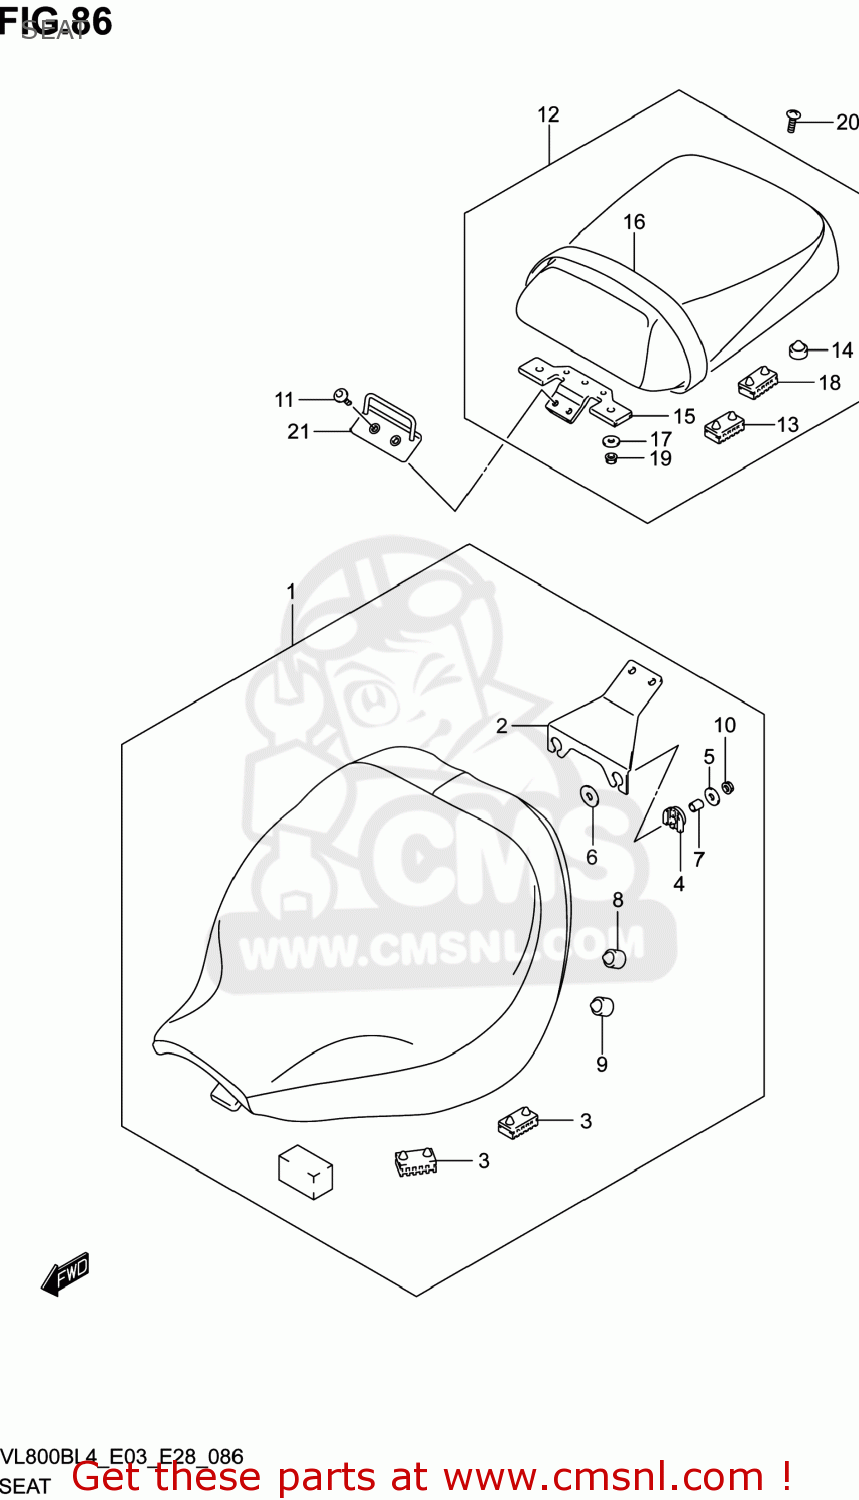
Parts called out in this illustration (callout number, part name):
1	SEAT ASSY
2	BRACKET,SEAT
3	CUSHION,SEAT(40X20X15)
4	CUSHION,SEAT BRACKET
5	WASHER(6.5X20X1.6)
6	WASHER(6.5X24X1.6)
7	SPACER(6.5X10X11)
8	CUSHION(11.5X22X20)
9	CUSHION
10	NUT
11	BOLT(6X18)
12	SEAT ASSY,PILLION
13	CUSHION,SEAT(40X20X15)
14	CUSHION,RR
15	BRACKET,PILLION SEAT
16	BAND,SEAT PILLION(BLACK)
17	WASHER(6.5X20X1.6)
18	CUSHION(11.5X22X20)
19	NUT
20	BOLT(8X16)
21	BRACKET,SEAT SUPPORT
